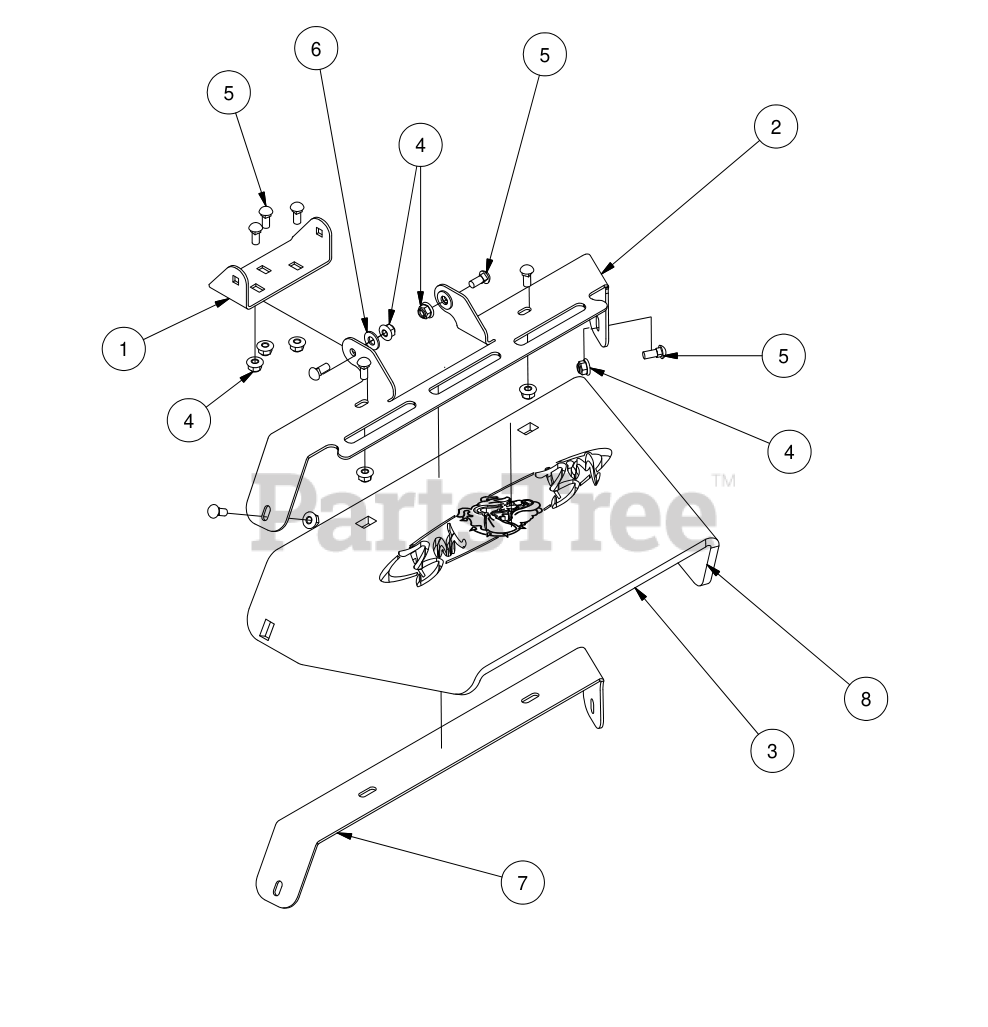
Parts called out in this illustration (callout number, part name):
1	Chute Hanger
2	Discharge Chute Bracket MZ (Upper)
3	Rubber Discharge Chute MZ (Component)
4	5/16" Nylon Flange Nut
5	5/16-18x3/4 carriage bolt
6	.360 ID Plastic Washer
7	Discharge Chute Bracket MZ (Lower)
8	Parts 2,3,5,7,8 Make's up the Mz discharge Assembly
